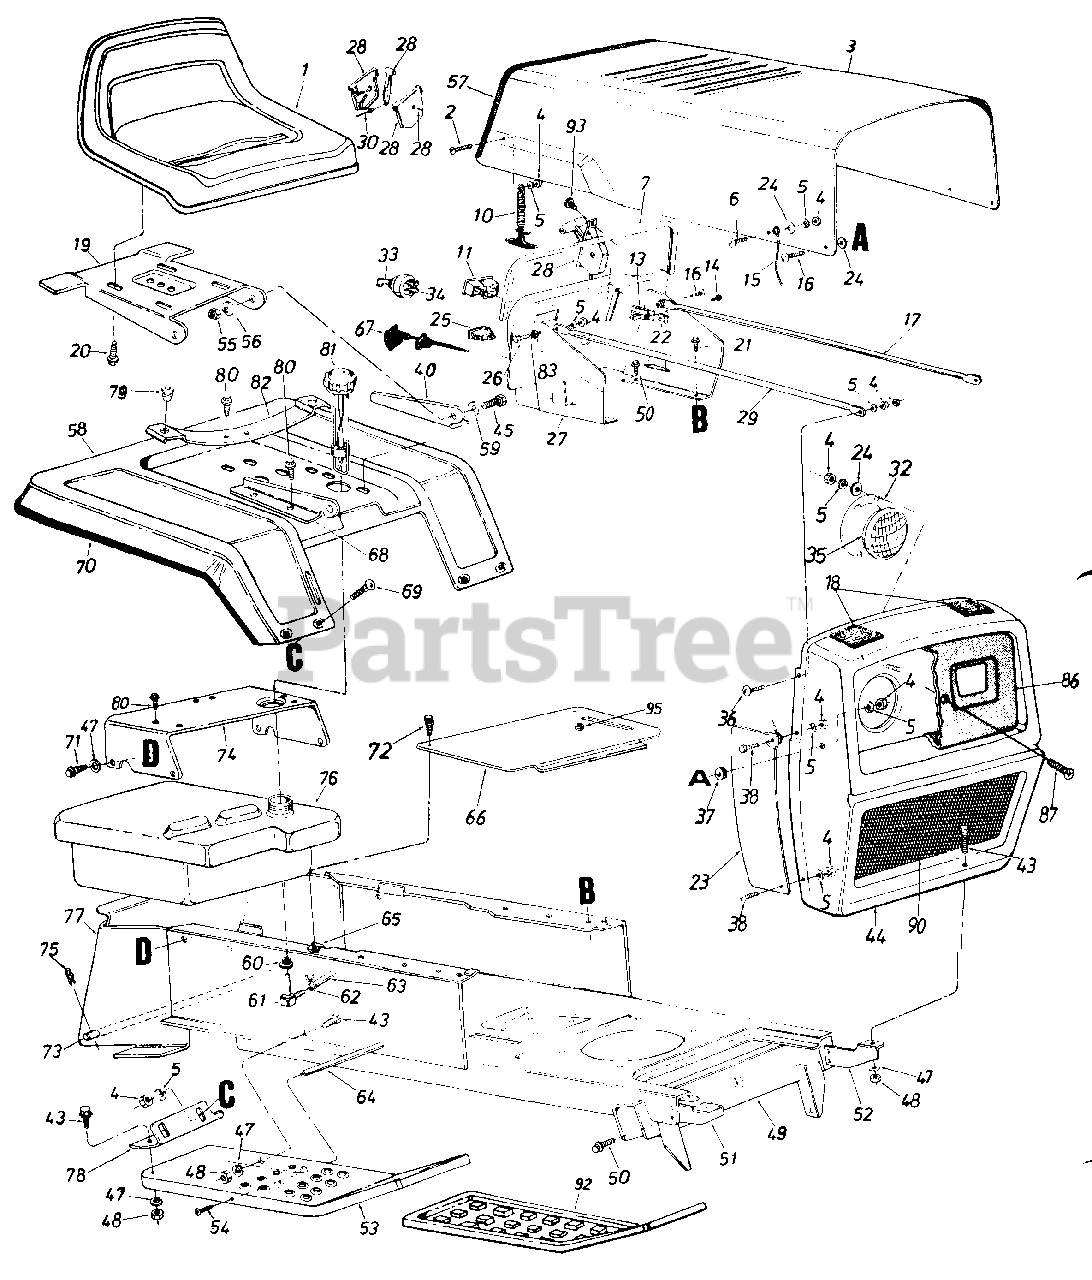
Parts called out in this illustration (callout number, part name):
1	Seat Assembly
2	Truss Mach. Scr. 1/4-20 x .50" Lg.
5	L-Wash. 1/4" Scr.
6	Truss Mach. Scr. 1/4-20 x .50" Lg.*
7	Vinyl Molding Strip-29"
10	Hood Latch Ass'y.
11	Ammeter
13	Circuit Breaker 8 Amp.
14	Hex Tap Scr. #10 x .50" Lg.
15	Hood Stop
16	Truss Mach. Scr. 1/4-20 x .75" Lg.
17	Grille Positioning Rod
18	PVC Foam Strip 1/2 x 1.00" x 2.00" Lg.
19	Seat Pivot Brkt.
20	Hex Wash. Hd. AB-Tap Scr. 3/8 x .75" Lg.
21	Hex Thd. Rolling Scr. 1/4" x .50" Lg.
22	Speed Nut #10Z
23	Grille Side Panel-R.H.
24	Fl-Wash. 1/4" I.D.
25	Light Switch
26	Truss Hd. Scr. 1/4-20 x 1.00" Lg.
27	Dash Panel Ass'y.
28	Throttle Control Box Comp.
29	Grille Positioning Rod
30	Throttle Control Cable
32	Head Lamp Retainer
33	Ignition Key
34	Ignition Switch
35	Head Lamp
36	Truss Machine Scr. 1/4-2O x .75" Lg.
37	Rubber Wash. .50" I.D. x 1.00 O.D. x .25 Thk.
38	Truss Mach. Scr. 1/4-20 x .50" Lg.
40	Seat Bracket-L.H.
43	Hex Scr. 5/16-18 x .75" Lg.
44	Grille Ass'y.
45	Hex Bolt 5/16-18 x .75" Lg.
47	L-Wash. 5/16" I.D.
48	Hex Nut 5/16-18 Thd.
49	Lower Frame Ass'y.
50	Hex Thd. Rolling Scr. 5/16" x.75" Lg.
51	Grille Mount Brkt.-R.H.
52	Grille Mount Brkt.-L.H.
53	Running Board-R.H.
54	Truss Mach. Scr. 5/16-18 x .75" Lg.
55	Hex Cent. L-Nut 5/16-18 Thd.
56	Bell-Wash. .34" I.D. x .88 O.D.
57	Vinyl Moulding Strip-30"
60	Bushing
61	90ø Nipple
62	Hose Clamp 3/8"
63	Gas Line 46" Lg.
64	Running Board Rod
65	Speed Nut #10-24
66	Transmission Cover Ass'y.
67	Choke Control Comp.
68	Seat Bracket-R.H.
69	Carr. Bolt 1/4-20 x .50" Lg.
70	Trim Strip-81" Lg.
71	Hex Thd. Rolling Scr. 5/16-24 x .75" Lg.
72	Truss Hd. Scr. #10 x .50" Lg.
73	Hitch Rod
74	Seat Mounting Channel
75	Internal Cotter Pin
76	Gas Tank
77	Hitch Plate
80	Hex Wash. Hd. Self-Tap Scr. 5/16-18 x .50" Lg.
81	Gas Gauge
82	Seat Spring
83	External Wash. 1/4" I.D.
86	Headlight Bezel
87	Hex Wash. Hd. F-Tap Scr. #8-32 x .38" Lg.
90	Grille Screen
92	Foot Pad
93	Truss Mach. AB-Tap Scr. #10 x .50" Lg.
95	Snap Bushing
